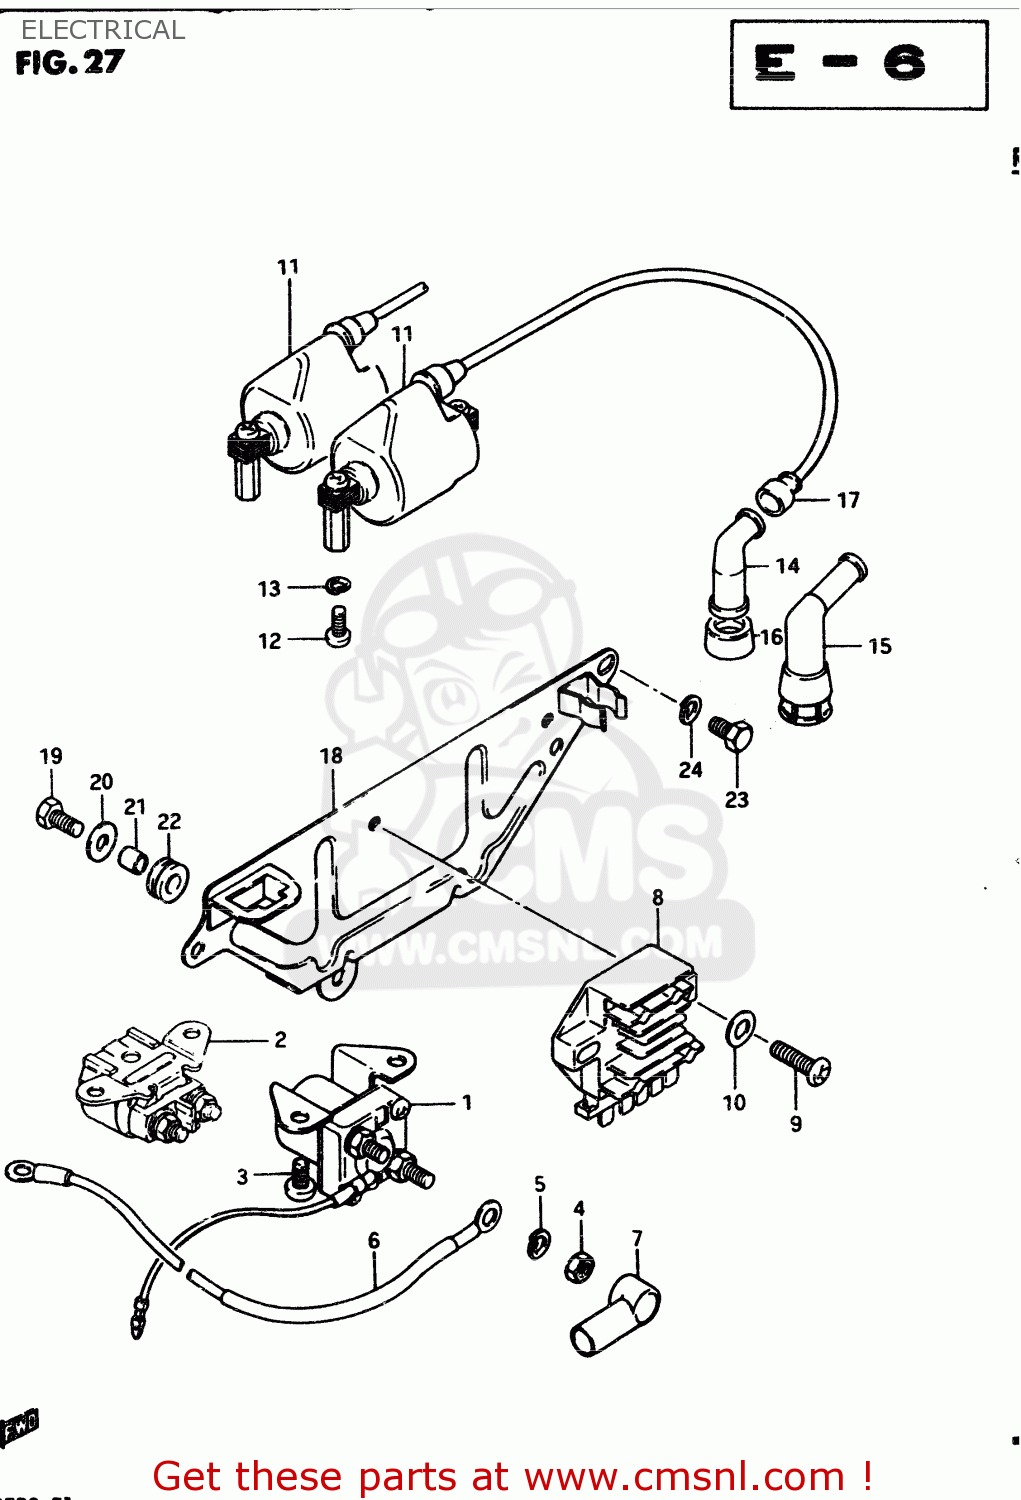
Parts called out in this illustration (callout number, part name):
1	RELAY ASSY,STARTING MOTOR
2	RELAY ASSEMBLY,STARTING MOTOR
3	SCREW
4	NUT 6MM
5	LOCK WASHER
6	CORD,BATTERY MINUS
7	CAP,STARTER RELAY
8	RECTIFIER ASSEMBLY
9	SCREW
10	WASHER
11	COIL ASSEMBLY,IGNITION
12	SCREW
13	LOCK WASHER
14	CAP,SPARK PLUG
15	CAP, SPARK PLUG (S)
16	SEAL,SPARK PLUG
17	SEAL,SPARK PLU
18	HOLDER COMP,ELECTRONIC PARTS
19	BOLT
20	WASHER
21	SPACER (6.1X8X9.5)
22	CUSHION
23	BOLT
24	LOCK WASHER
